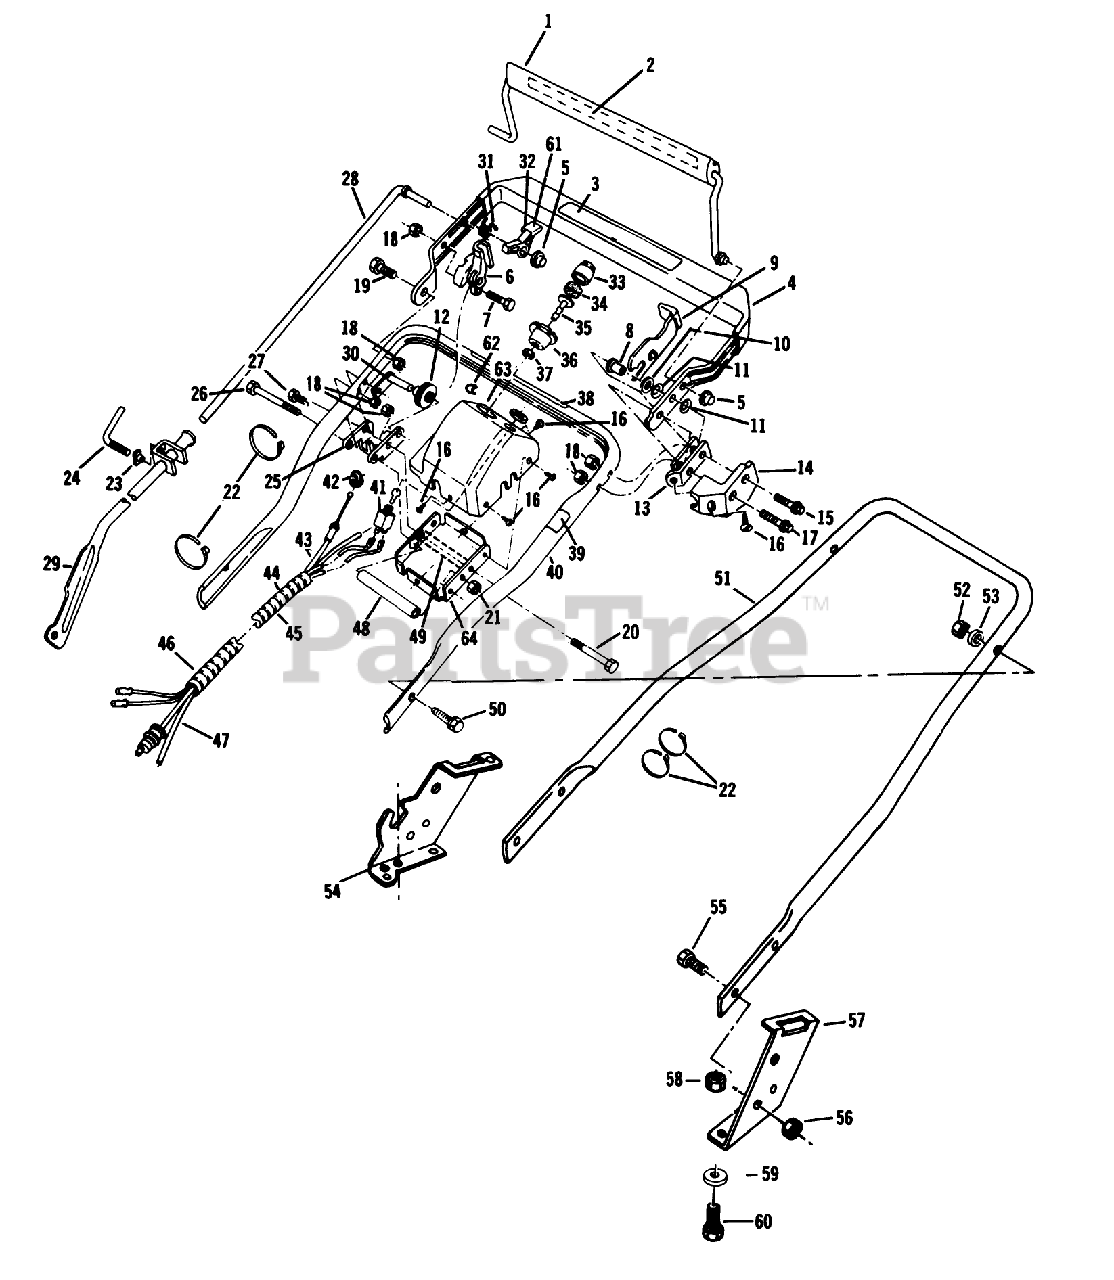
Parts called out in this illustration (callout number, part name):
10	WASHER M
13	DOWN STOP
14	LOCKOUT GUARD
15	BOLT SHOU
16	SCREW F
18	LOCKNUT E
26	BOLT-CONSOLE
34	FILTER S
37	LOCKNUT S
39	PULLEY UPPER PL
41	SWITCH AY
42	RET. RING
43	CONTROL CABLE
52	NUT-LOCK F
53	WASHER-CURVED
56	NUT-JAM, LOCKING
58	NUT-LOCK F
